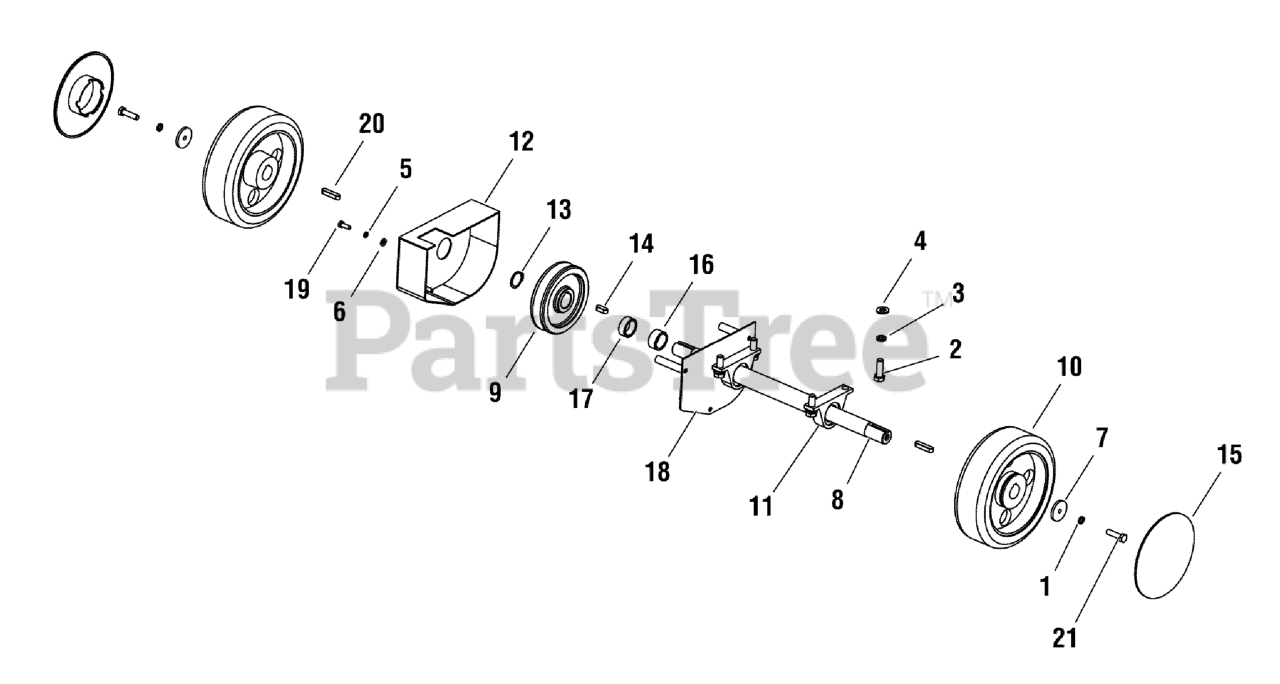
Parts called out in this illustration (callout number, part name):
1	WASHER, Spring, 8
2	WASHER, Spring, 8
3	WASHER, Flat
4	BOLT, Hex, M10 x 30
5	WASHER, Spring
6	WASHER, Flat
7	WASHER, Flat
8	SHAFT, Rear Wheel
9	WORM WHEEL
10	WHEEL, Rear
11	BEARING
12	SHUCK SEAM, Worm Wheel
13	CIRCLIP
15	COVER, Rear Wheel
16	BUSHING
17	BUSHING
18	COVER, Worm Wheel
19	BOLT, Hex, M6 x 16
21	BOLT, Hex, M8 x 30
